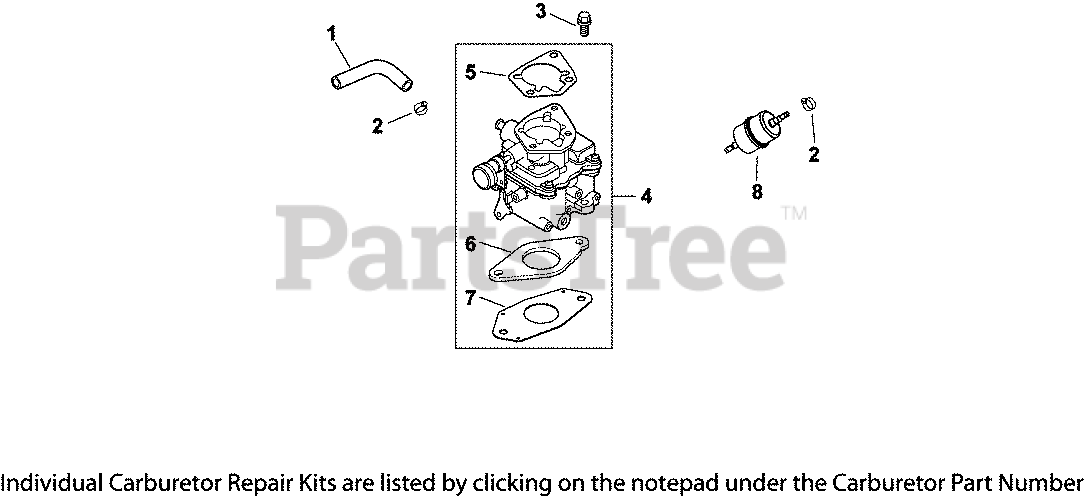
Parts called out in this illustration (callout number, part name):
1	HOSE,LW PERM.FUEL 24.00"-USE 25 111 81-S
2	CLAMP, HOSE (KM)-USE 25 237 31-S
3	SCREW, FLG M6X1.0X30
4	KIT,CARB(KEIHIN) W/GASKETS
5	GASKET, AIR CLEANER BASE
6	GASKET, CARBURETOR
7	GASKET, CARBURETOR
8	FILTER, FUEL
